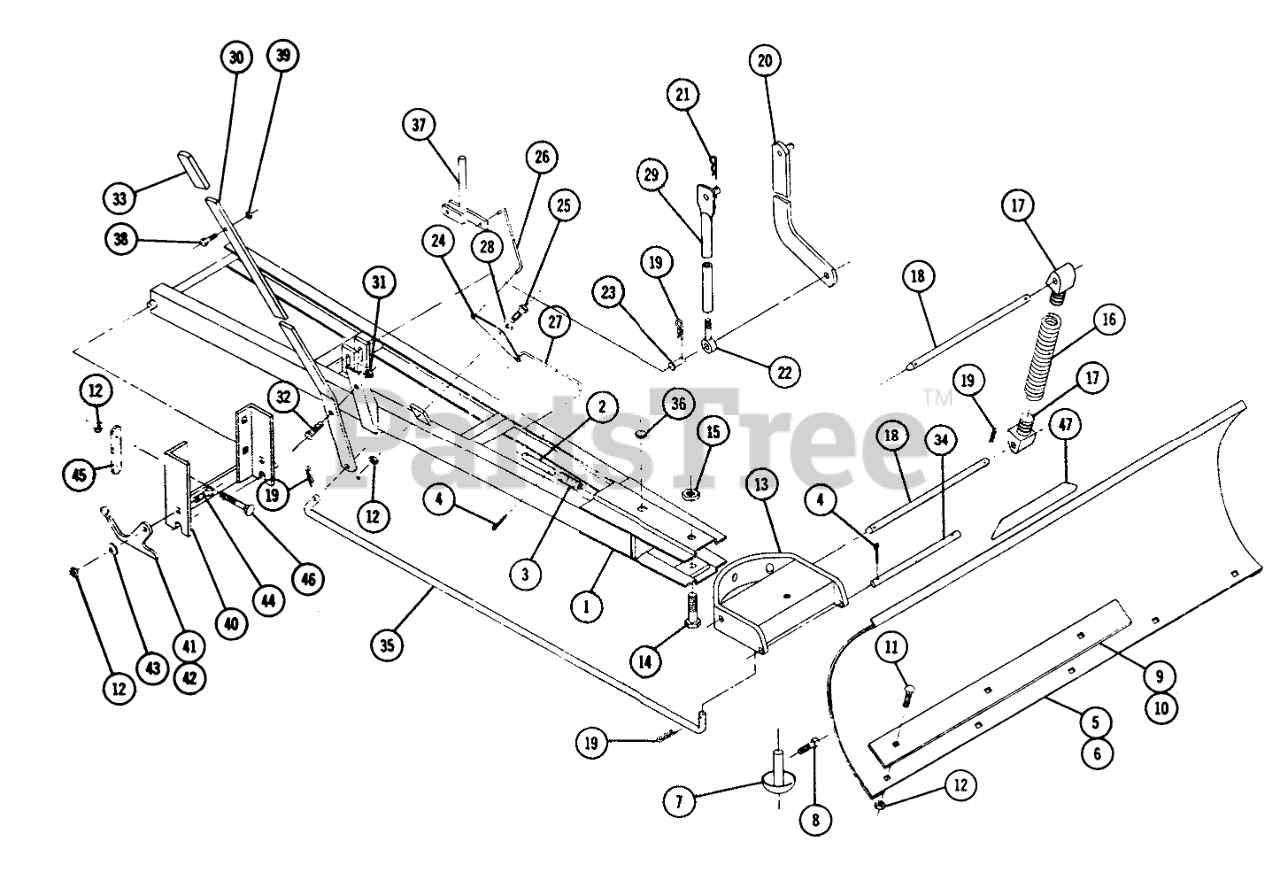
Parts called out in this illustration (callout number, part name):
1	Ass-y-Frame
2	Index Pin
3	SPRING-COMPRESSION
4	Cotter Pin
5	Blade
6	Ass-y-Blade
7	Skid
8	Set Screw 3/8-16
9	Plate
10	Plate-Blade Edge
11	Bolt-3/8-16 x 3/4
12	3/8-16 E.S.
13	Sector and Channel
14	Bolt Hex 3/4-16 x 3 3/4
15	Nut-3/4-16 E.S.
16	Spring
17	Lug
18	ROD-PIVOT, BLADE
19	Hairpin
20	Ass-y. Lift Bar
21	Hairpin
22	Rod End
24	Index Plate
25	Bolt 3/8-16 x 1
26	Rod-Upper Index
27	Head-Cylinder
28	Washer
29	LIFT ROD
30	Lever-Index
31	Nut-1/2-13
32	Bolt Hex 1/2-13 x 1
33	GRIP
34	ROD-LOWER
35	Rod-Blade Control
36	PLUG
37	INDEX LEVER
38	Bolt-Hex 1/4-20
39	Nut-Nylok
40	Ass-y Bracket-Mtg.
41	Plate-Latching R.H.
42	Plate-Latching L.H.
43	Washer-Spring
44	Bolt 3/8-16 x 1
45	BRACKET-REAR LINK MOUNTING
46	Bolt-Carriage 3/8-16 x 3 1/4
47	Decal
